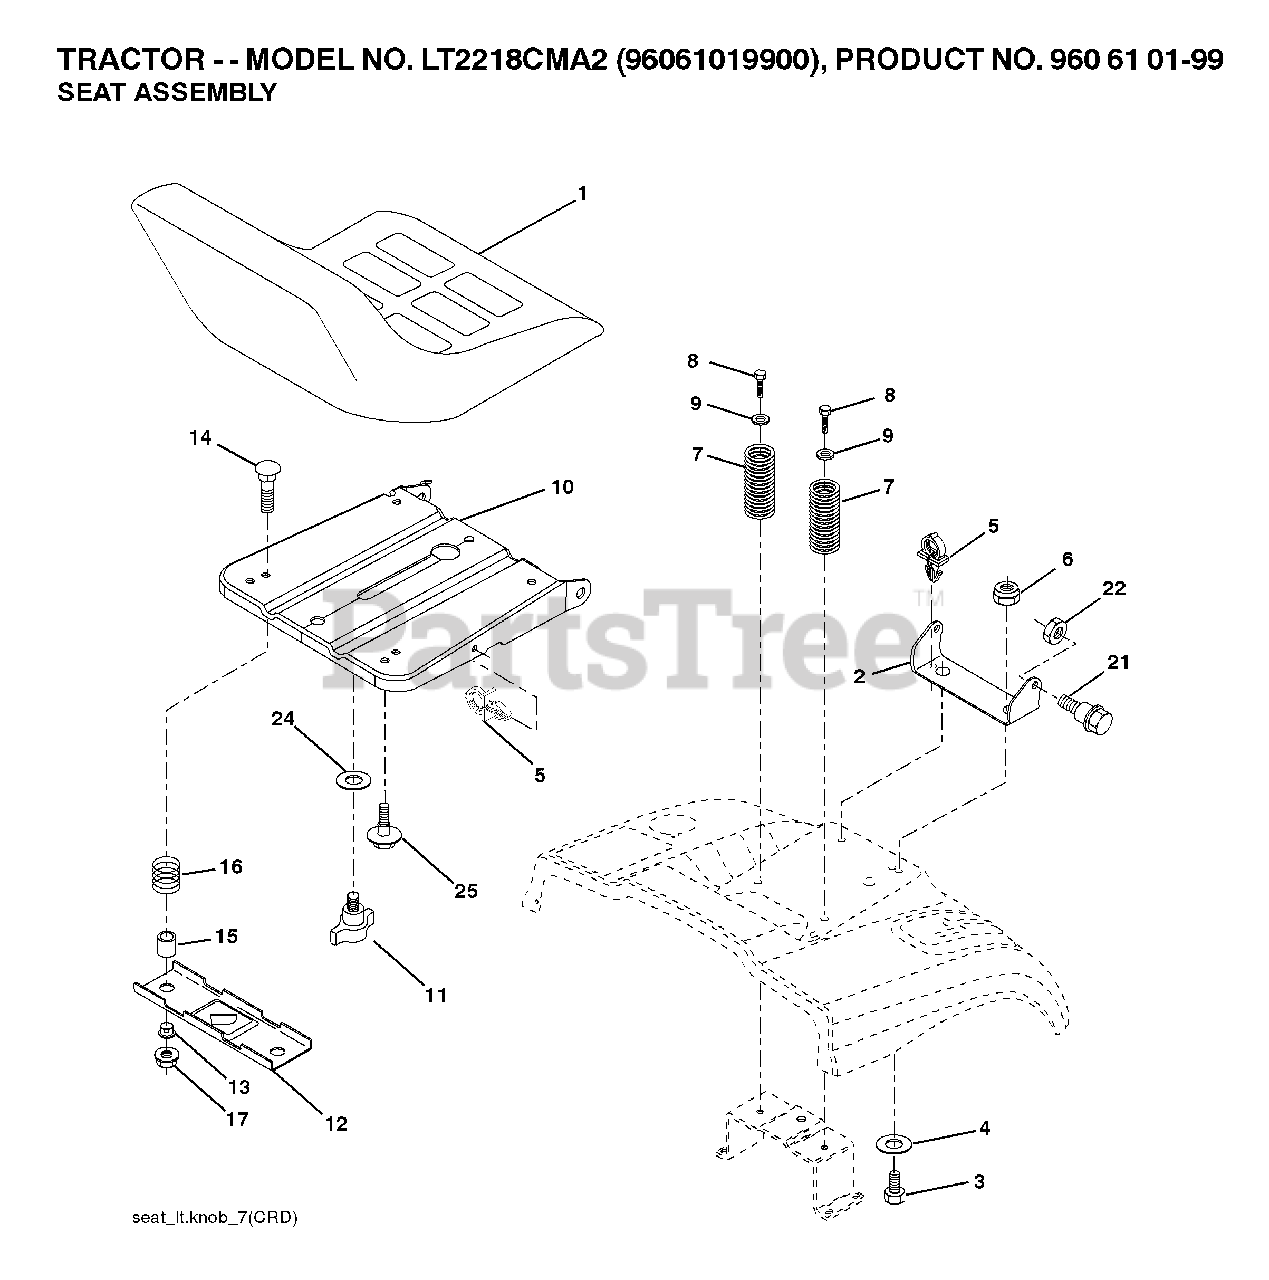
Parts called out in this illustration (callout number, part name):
1	SEAT.XG150.BLK.KB/SLD.NO-LOGO
2	SEAT PIVOT BRKT
4	WASHER PM
5	PUSH CLIP
6	NUT
7	SPRING COMPRESSION
8	SCREW 3/8-16X1
9	WASHER
10	PAN.ASM.SEAT.1SLOT
11	KNOB.SEAT.ADJ.WINGNUT
12	BRKT.MNTNG.SWITCH.SEAT
14	BOLT.ROUND.HEAD.SQUARE.NECK
15	SPACER SPLIT
16	SPRING COMPRESSED
17	NUT T
21	BOLT.SHOULDER.5/16-18
22	NUT.71038.31-18.HEX.NYLOCK
25	BOLT,SHOULD
